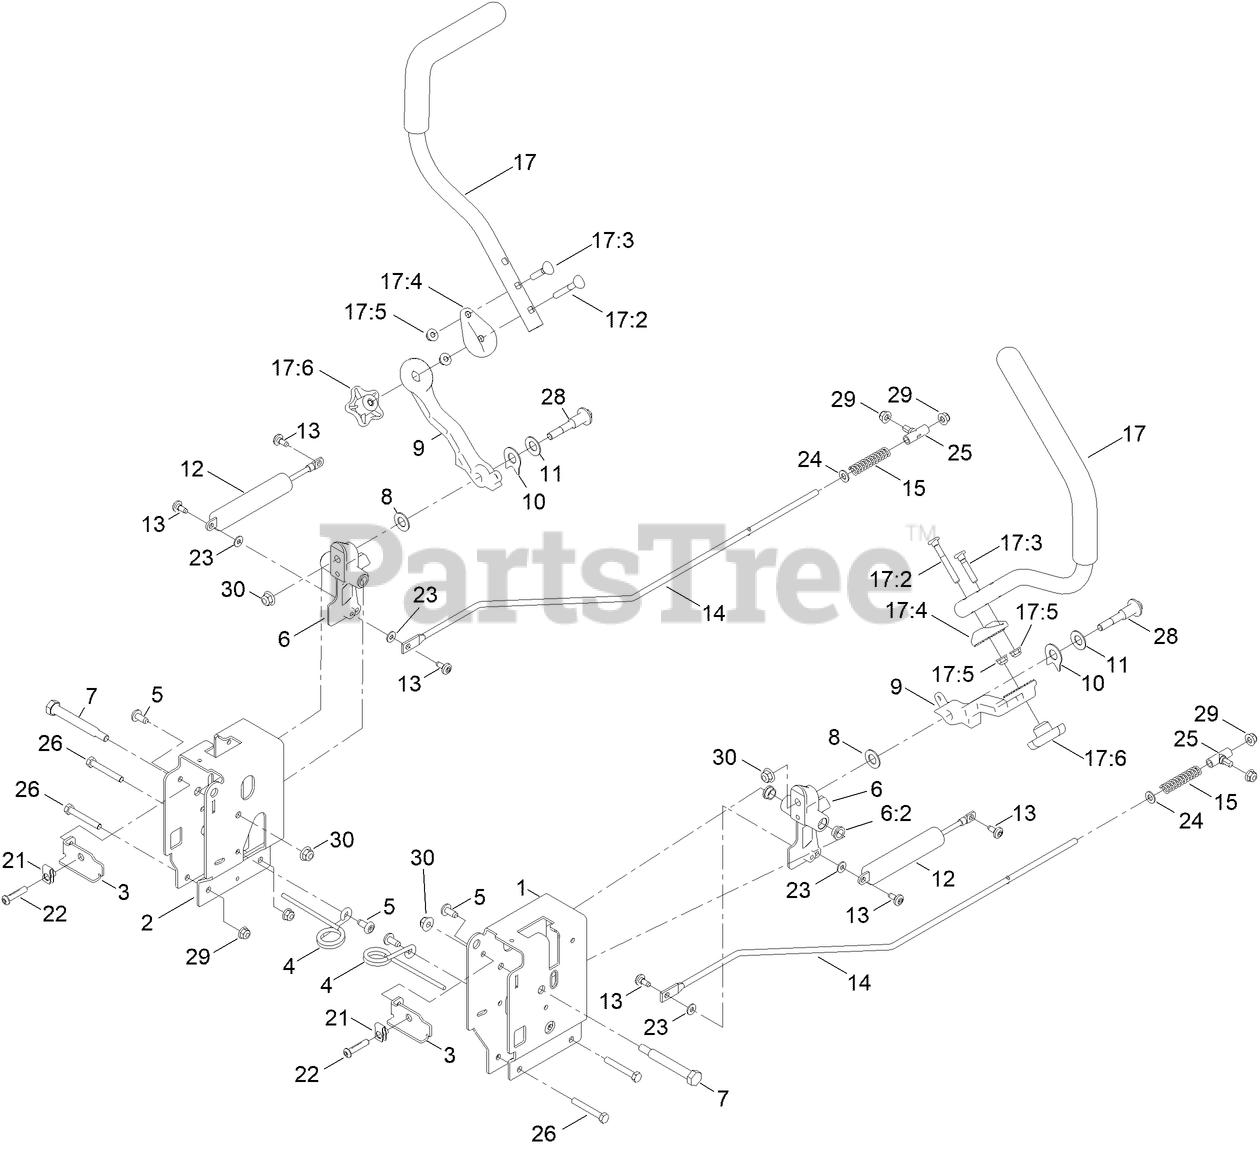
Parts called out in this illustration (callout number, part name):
1	CONTROL BOX - LH G7
2	CONTROL BOX - RH G7
3	ADJUSTMENT PLATE-CONTROL BOX
4	SPRING-TORSION
6	PIVOT ARM ASM
6:2	BUSHING-FLANGE
7	BOLT-PIVOT
8	WASHER-NYLON
9	ARM-CONTROL, 32 TEETH
10	SPACER, ANTI-ROTATION
11	WASHER-BELLEVILLE
12	DAMPER - NON CAVITATING
13	SCREW-SHOULDER
14	ROD - HYDRO, LH
15	SPRING-COMPRESSION
17	HANDLE-CONTROL, ASM
17:2	SCREW-HANDLE
17:3	SCREW-HANDLE
17:4	DISC-ADJUSTMENT HANDLE, 32 TEETH
17:5	NUT-HF
17:6	KNOB-HANDLE
22	SCREW-HSBH
23	WASHER
24	WASHER-PLAIN
25	MOUNT-ROD, HYDRO
26	SCREW-HH
28	BOLT-PIVOT
29	NUT-HF, NI
30	NUT-HF, NI
